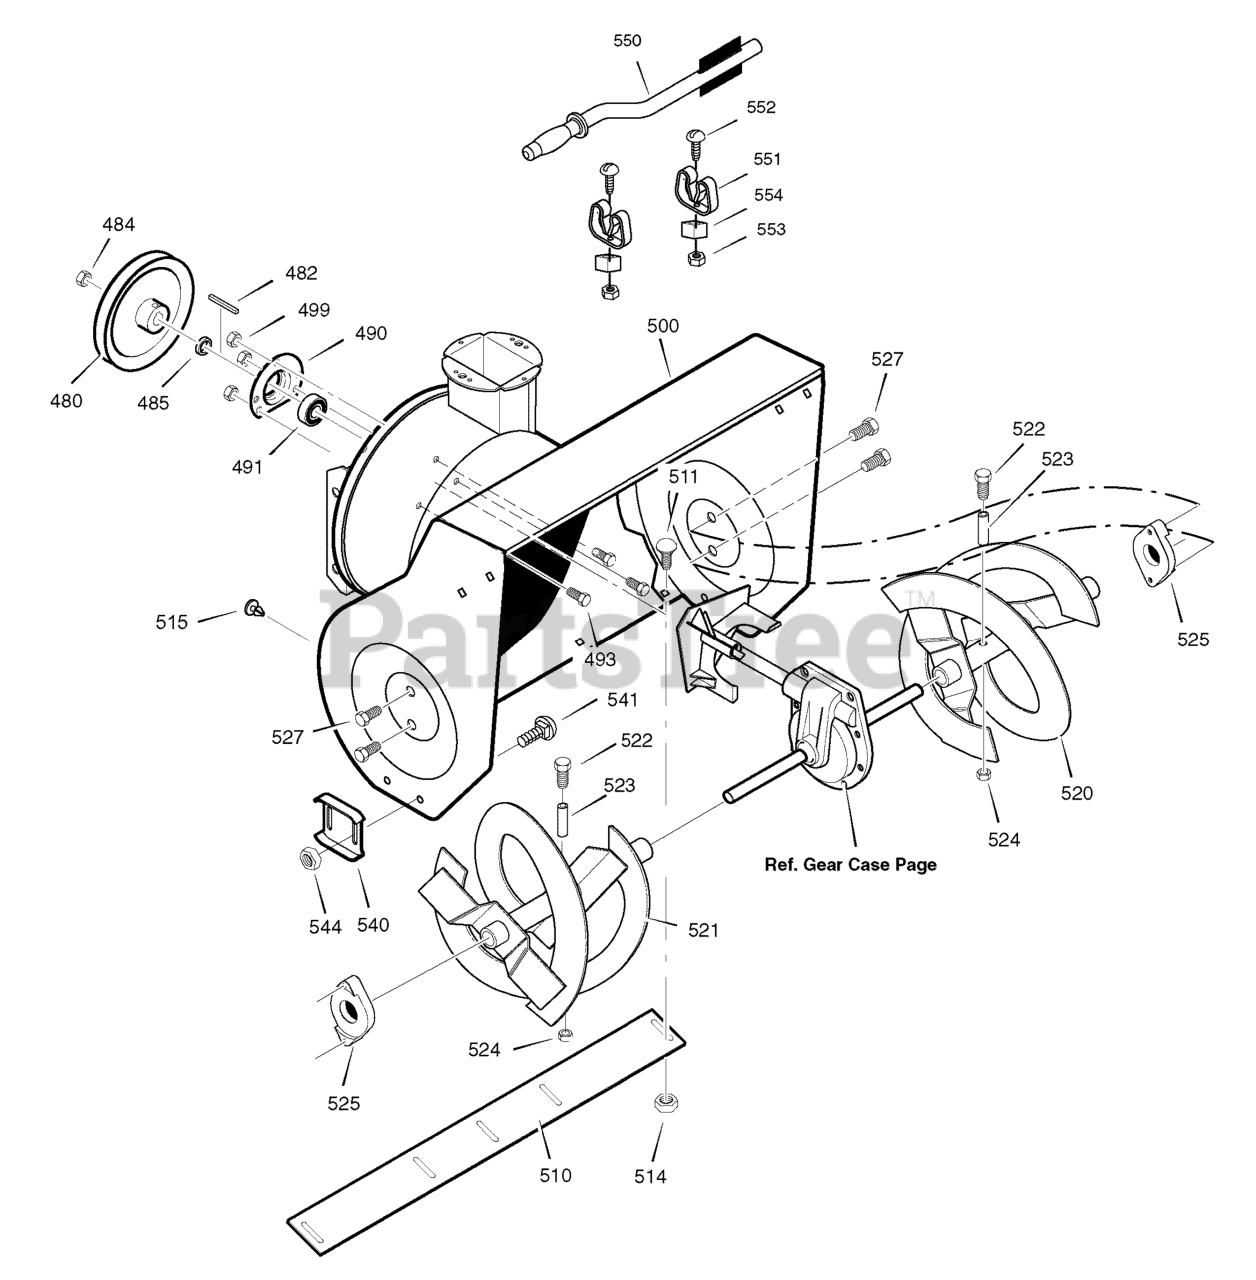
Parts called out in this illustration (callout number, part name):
480	PULLEY, 4L 8.40 OD
482	KEY, SQUARE 3/16 X 3/4
484	NUT, 1/2-20
485	SPACER, FRICTION PULLEY
490	RETAINER, BALL BEARING
491	BEARING, BALL
493	BOLT, HEX 5/16-18 X 0.62
499	NUT, 5/16-18 HEXWDFLLK
500	HOUSING, ASSEMBLY
510	BLADE, SCRAPER
511	BOLT, 5/16-18 X 0.75
514	NUT, 5/16-18
515	PLUG PANEL, BLACK
520	AUGER, ASSEMBLY, LH
521	AUGER, ASSEMBLY, RH
522	SCREW, 1/4-20 X 1.75
523	SPACER, SLEEVE
524	NUT, 1/4-20
525	BEARING, FLANGE
527	SCREW, 5/16-18 x 0.75
540	SKID, HEIGHT ADJUST
541	BOLT, 5/16-18 X 0.5
544	NUT, 5/16-18
550	BRUSH, CLEANOUT
551	CLIP, RETAINER
552	SCREW
553	NUT
